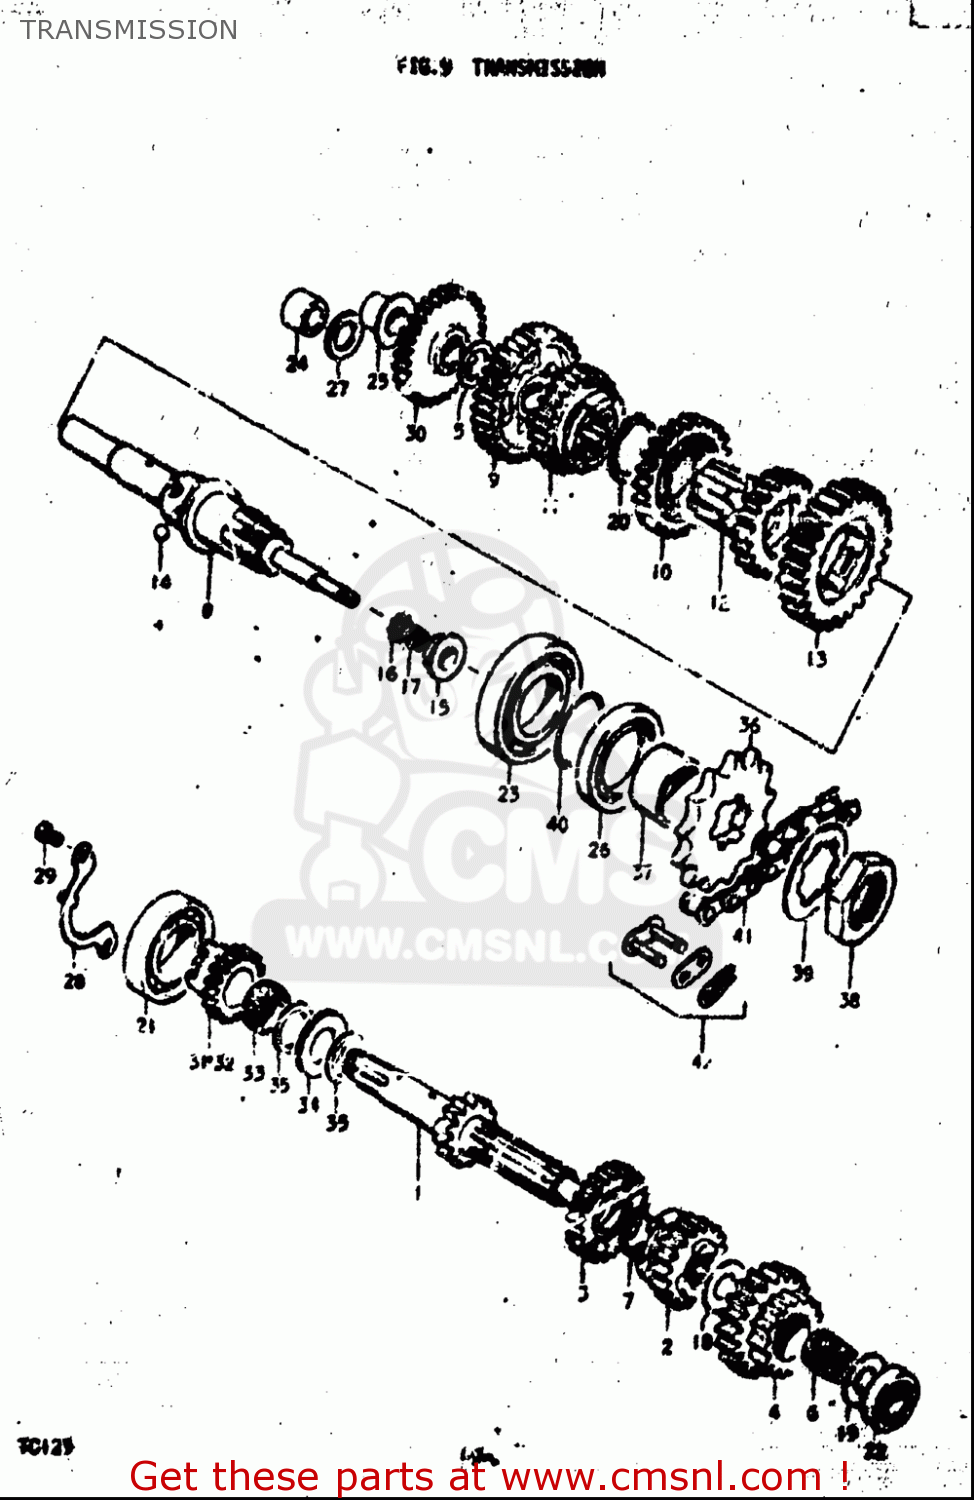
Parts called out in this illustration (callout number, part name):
5	SHIM, 15X24X1.0
7	CIRCLIP
14	BALL
15	OIL SEAL
17	NUT
18	SHIM, 15X24X1.0
19	WASHER
20	CIRCLIP
21	BEARING
22	BEARING
23	BEARING(25X52X15)
24	BUSH
26	SEAL,OIL(30X44X6)
27	WASHER
28	RETAINER,CNTR SHAFT BEARING
29	SCREW
31	GEAR,KICK STARTER IDLE
33	BEARING(19.2X23.2X19)
34	BEARING(21X32X2.85)
35	WASHER(21X30X0.8)
36	SPROCKET,ENGINE
37	SPACER (25X30X12.4)
38	NUT
39	WASHER,LOCK
40	O RING(D:1,ID:24.5)
41	CHAIN ASSEMBLY,DRIVE
